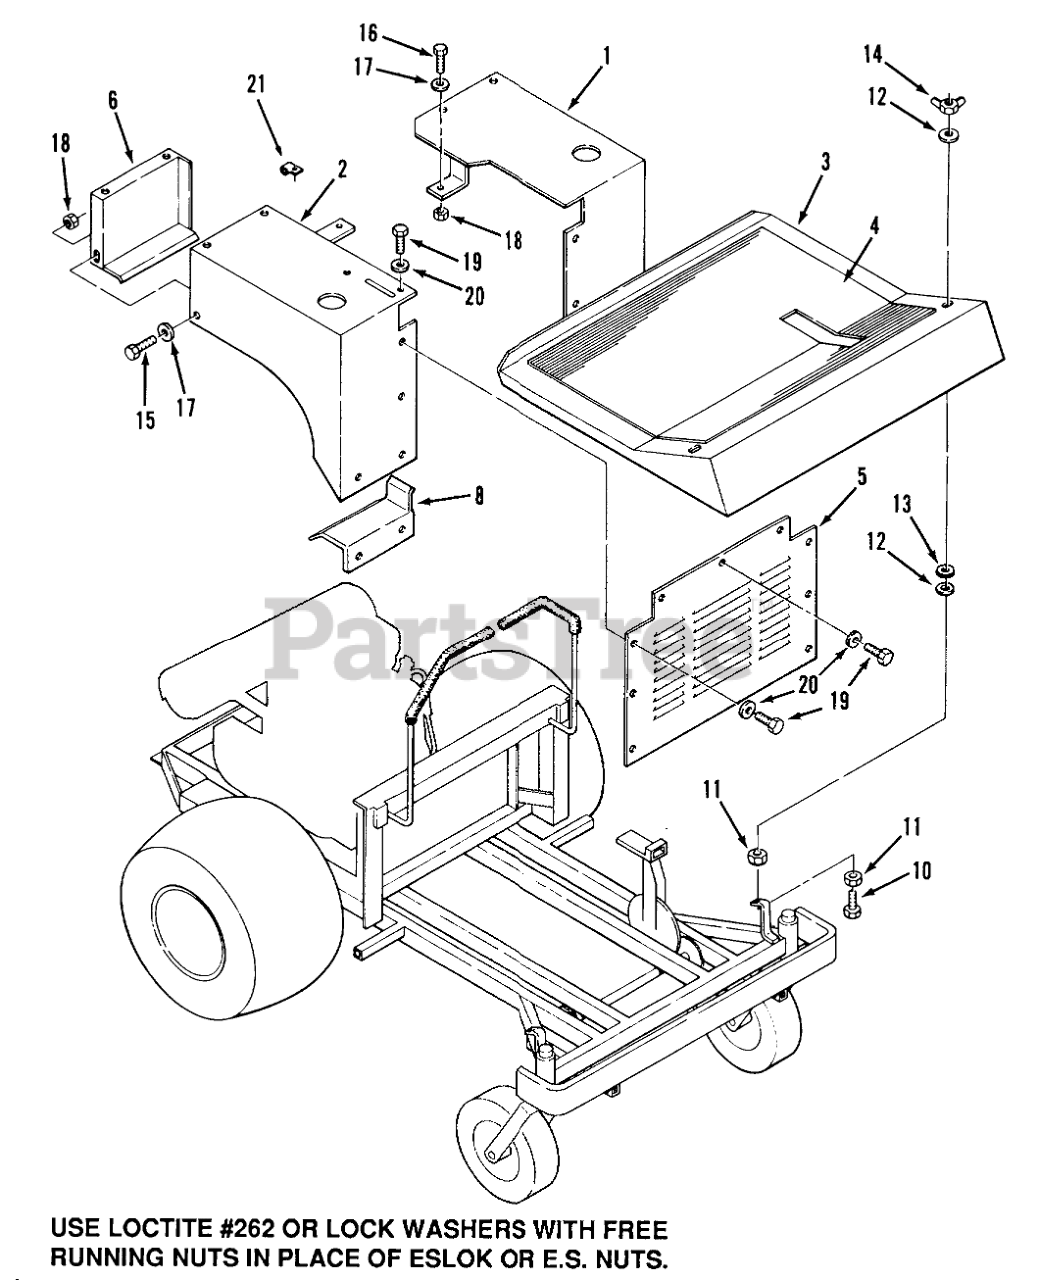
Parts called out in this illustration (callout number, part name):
1	Fender LH
2	FENDER - RH R
3	Floor Pan
4	Black Carpet
5	Front Panel
6	Bracket-Fender Rear RH
8	Bracket-Fender Frt RH
10	Full Thread Bolt 5/16 x 1-1/2
11	Nut
12	Washer
13	WASHER
14	WING NUT
15	H H C S
16	Bolt
18	Nut
19	Bolt
20	WASHER
21	J-CLIP
